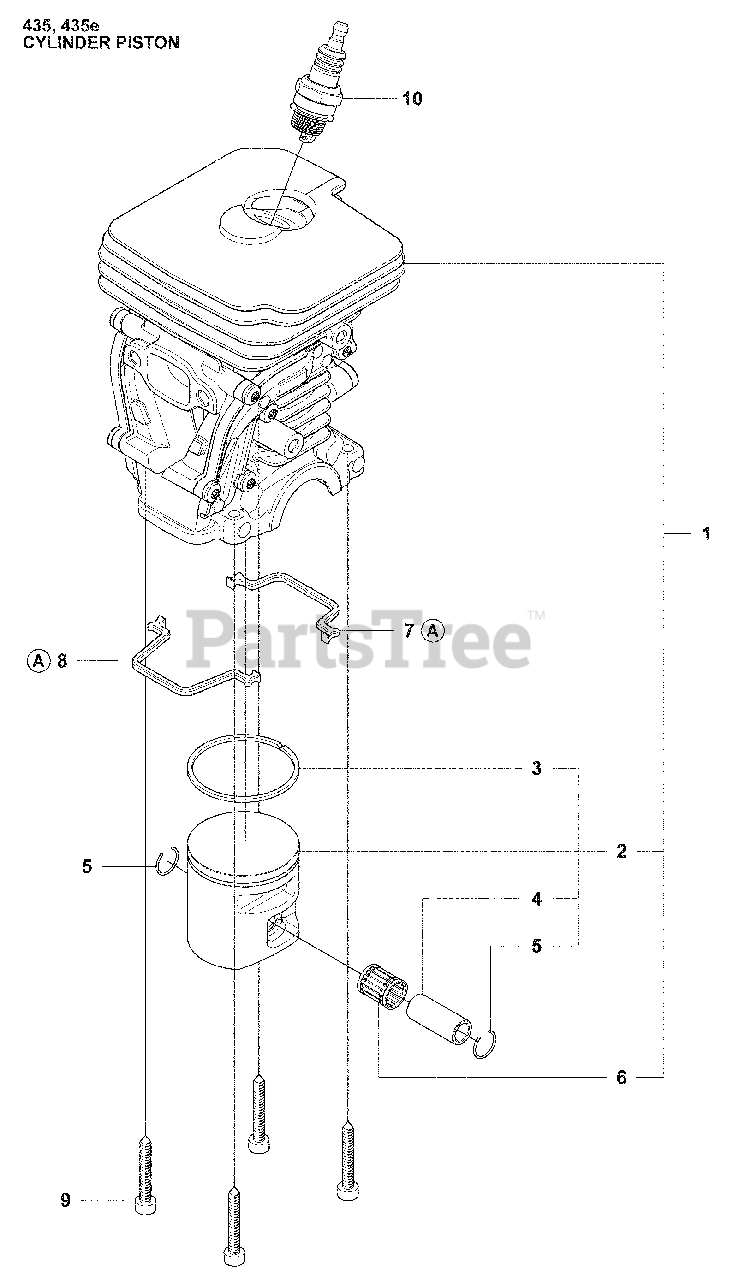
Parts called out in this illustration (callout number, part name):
1	Cylinder Assembly, 435 and 435E
2	Piston Assembly
3	Piston Ring
4	Piston Pin
5	Locking Ring
6	Support Bushing
7	Cylinder Gasket, Rear
8	Cylinder Gasket, Front
9	Screw, MC6S 5 X 25
10	Solid Spark Plug, BPMR7A
